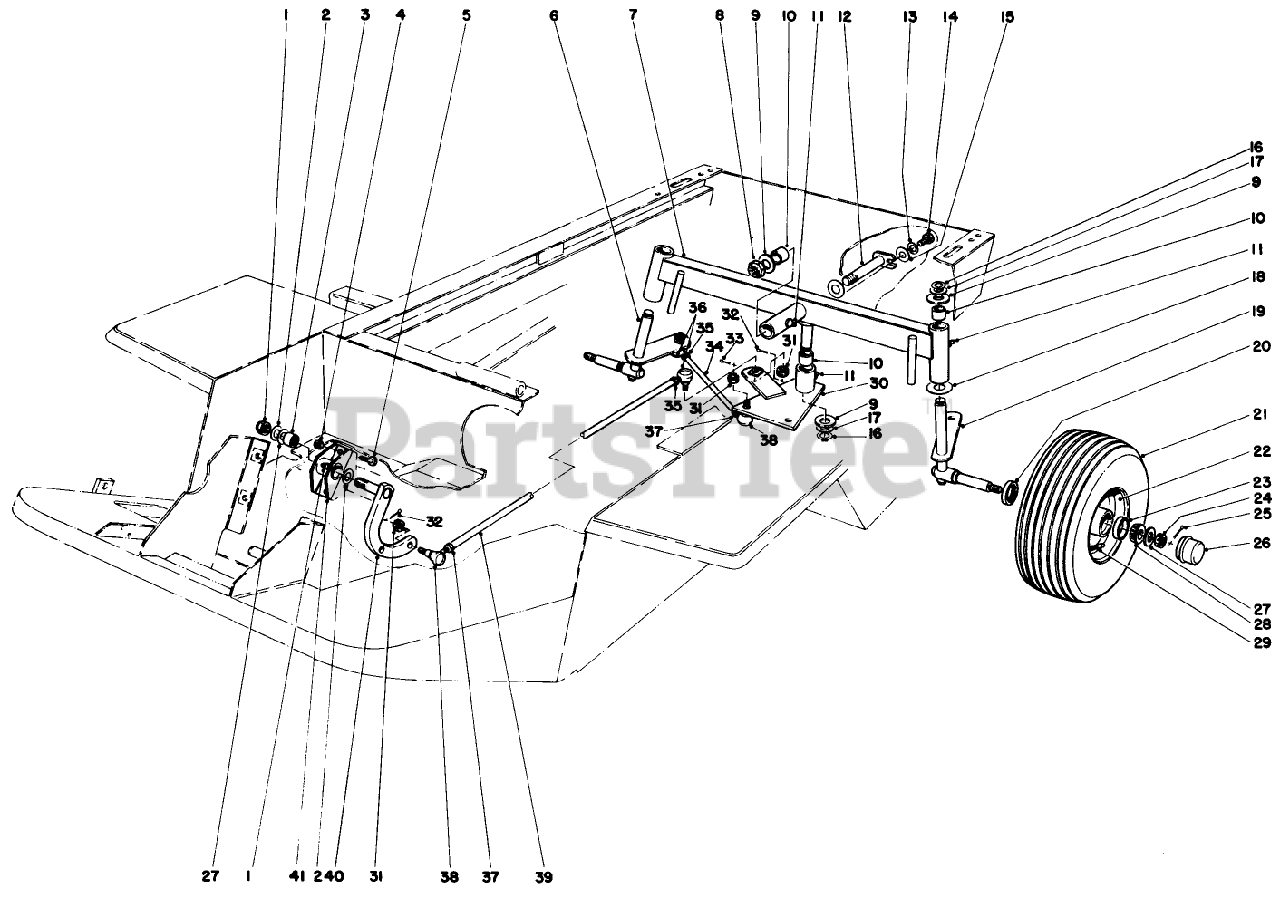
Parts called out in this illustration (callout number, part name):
1	NUT-LOCK, NI
2	THRUST WASHER
3	BEARING-NEEDLE
4	NUT-LOCK, NI
5	SCREW-HH
7	REAR AXLE WA
8	NUT-LOCK, NI
11	FITTING-GREASE
13	SCREW-HH
14	SCREW-HH
15	WASHER-FLAT
16	RING-RETAINING
17	WASHER
18	WASHER-THRUST
23	BEARING-CUP, TAPERED
24	NUT-HEX, SLOTTED
25	PIN-COTTER
26	CAP-DUST
27	WASHER-FLAT
28	BEARING-CONE, TAPERED
31	NUT-HEX,SLOTTED
33	SCREW-HH
35	NUT-HEX JAM LH
37	NUT-JAM
39	REAR STRG TUBE *PP
40	PIVOT ARM WA
